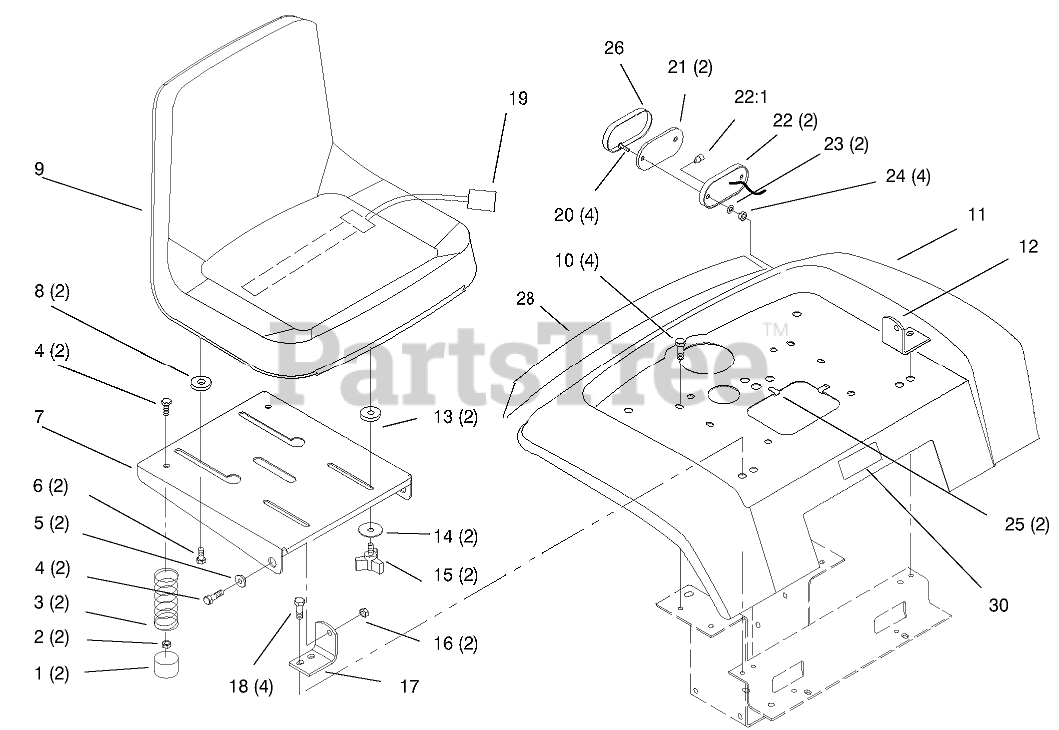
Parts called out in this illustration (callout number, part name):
1	CAP-PROTECTOR
2	NUT-LOCK, NI
3	SPRING-COMPRESSION
4	SCREW-HH
5	BUSHING
6	BOLT-SHOULDER
7	SUPPORT - SEAT (BLACK)
8	SPACER-NYLON
9	SEAT-V-511
10	Bolt
12	BRACKET-PIVOT, LH
13	SPACER-NYLON
14	WASHER
16	NUT-LOCK, NI
17	BRACKET-PIVOT, RH
18	SCREW-HWHTF
19	SWITCH-SEAT
20	SCREW-PPH
22	BASE-TAIL LIGHT
23	WASHER-LOCK, INT
24	NUT-LOCK, NI
25	SPEED CLIP
26	LENS-TAIL LIGHT
27	DECAL-DO NOT TOW
28	Decal-Rear Fender
30	DECAL - WHEELHORSE
